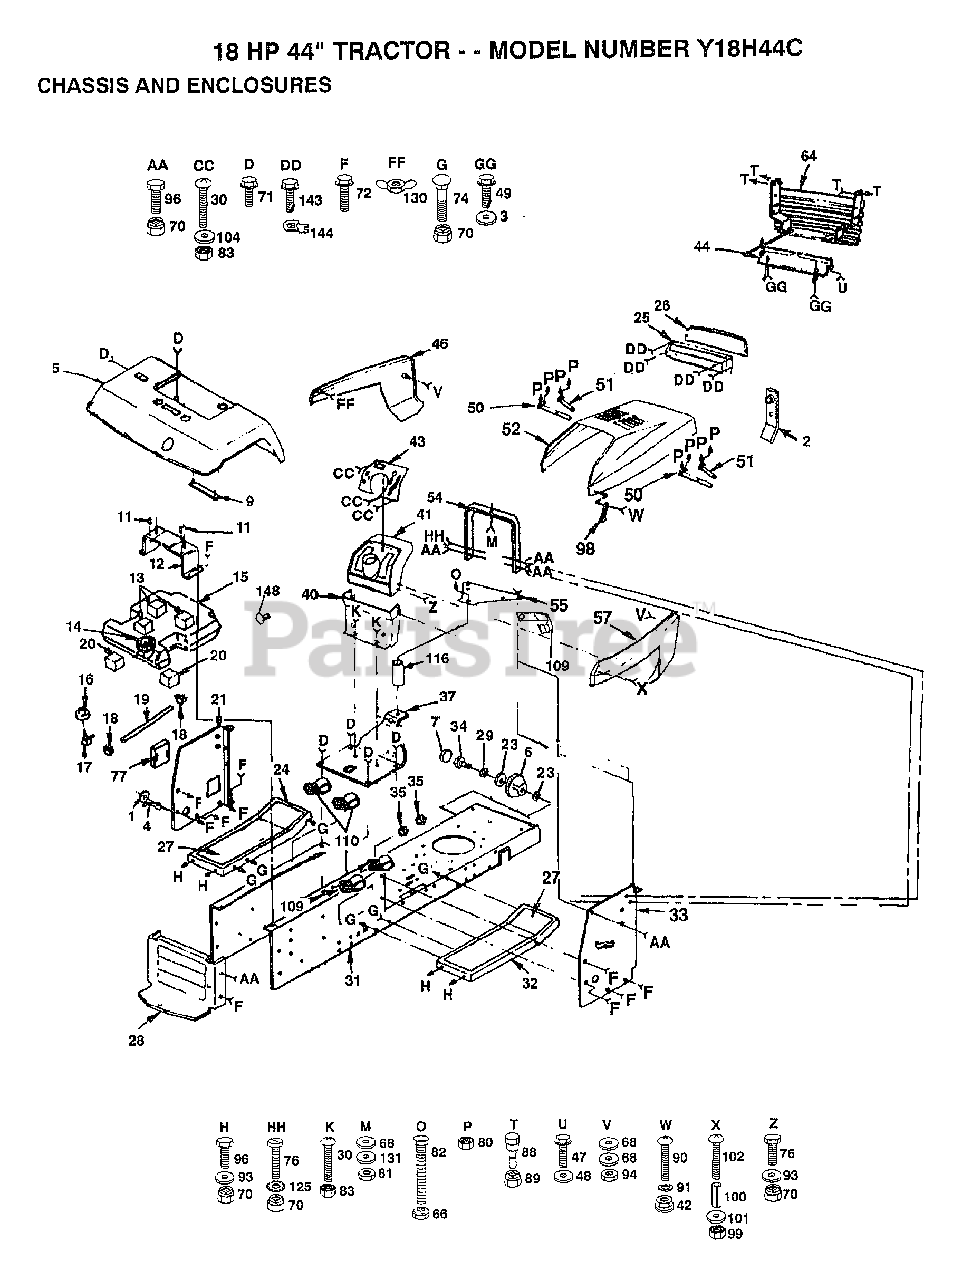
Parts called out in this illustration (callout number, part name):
1	WASHER T
3	WASHER
4	POINTER HGT IND
5	FENDER
6	HEIGHT INDICATOR
7	"PLUG,HOLE"
11	NUT-PUSH YT
12	BRKT.ASM.FENDER
13	PAD-SPACER LT
16	BUSHING OUTLET T
17	STEM.TANK.FUEL
18	HOSE CLAMP
20	PAD IDLER TI
21	PANEL.DASH.LH
23	WASHER
26	LENS LT
27	FOOTREST PAD
29	LOCKWASHER
30	SCREW
31	CHASSIS
33	PANEL.DASH.RH
40	LOWER DASH
42	WELDNUT
43	PLATE.DASH.SLK
47	SCREW HEX CRT
48	WASHER
49	SCREW
54	SUPPORT ASS'Y
57	"PANEL,SIDE RH "
68	WASHER PM
71	SCREW LT
72	SCREW
74	BOLT
76	BOLT
77	COVER ACCESS
80	NUT
82	BOLT
90	SCREW
91	LOCKWASHER
93	WASHER
98	HOOD LATCH T
100	SPACER LT
101	WASHER
102	SCREW
104	WASHER
109	CLIP T
110	"CLIP,INSULATOR"
116	SPACER
125	LOCKWASHER
131	LOCKWASHER
144	"""J"" FASTENER LT"
148	PLUG-DASH T
